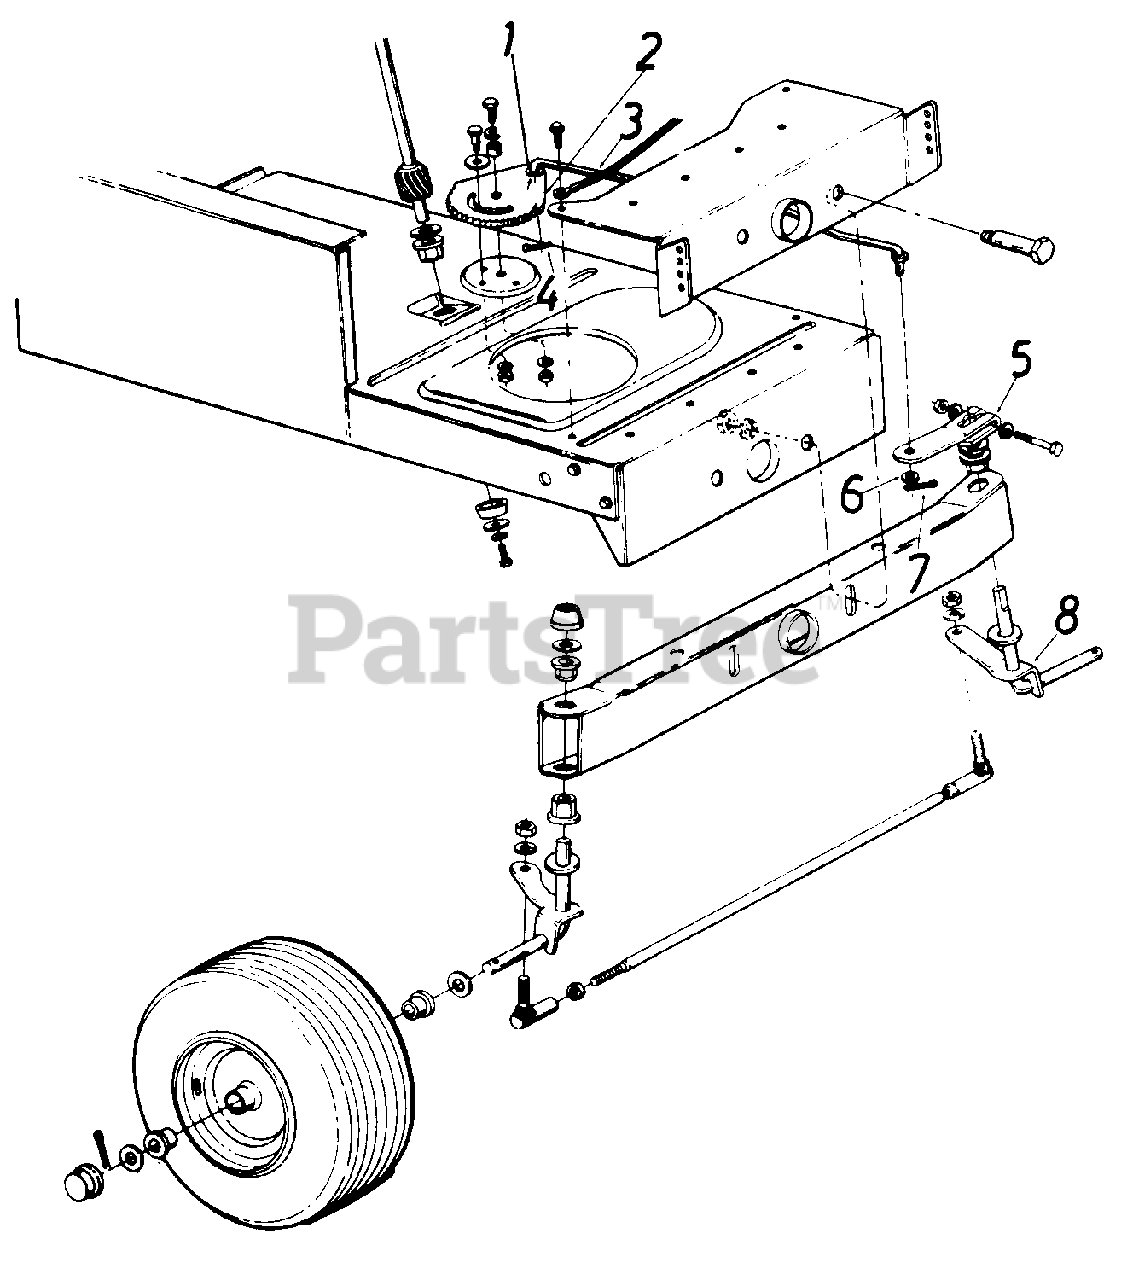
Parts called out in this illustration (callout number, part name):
1	Fl.-Wash. .56" I.D. x 1" O.D.
2	Steering Gear Segment
3	Steering Drag Link
4	Cotter Pin1/8" Dia. x 1" Lg.
5	Steering Arm F ront Axle
6	Fl.-Wash. .56" I.D. x 1" O.D.
7	Cotter Pin 1/8" Dia. x 1 " Lg.
8	Front Axle Ass'y.-L.H. Short
